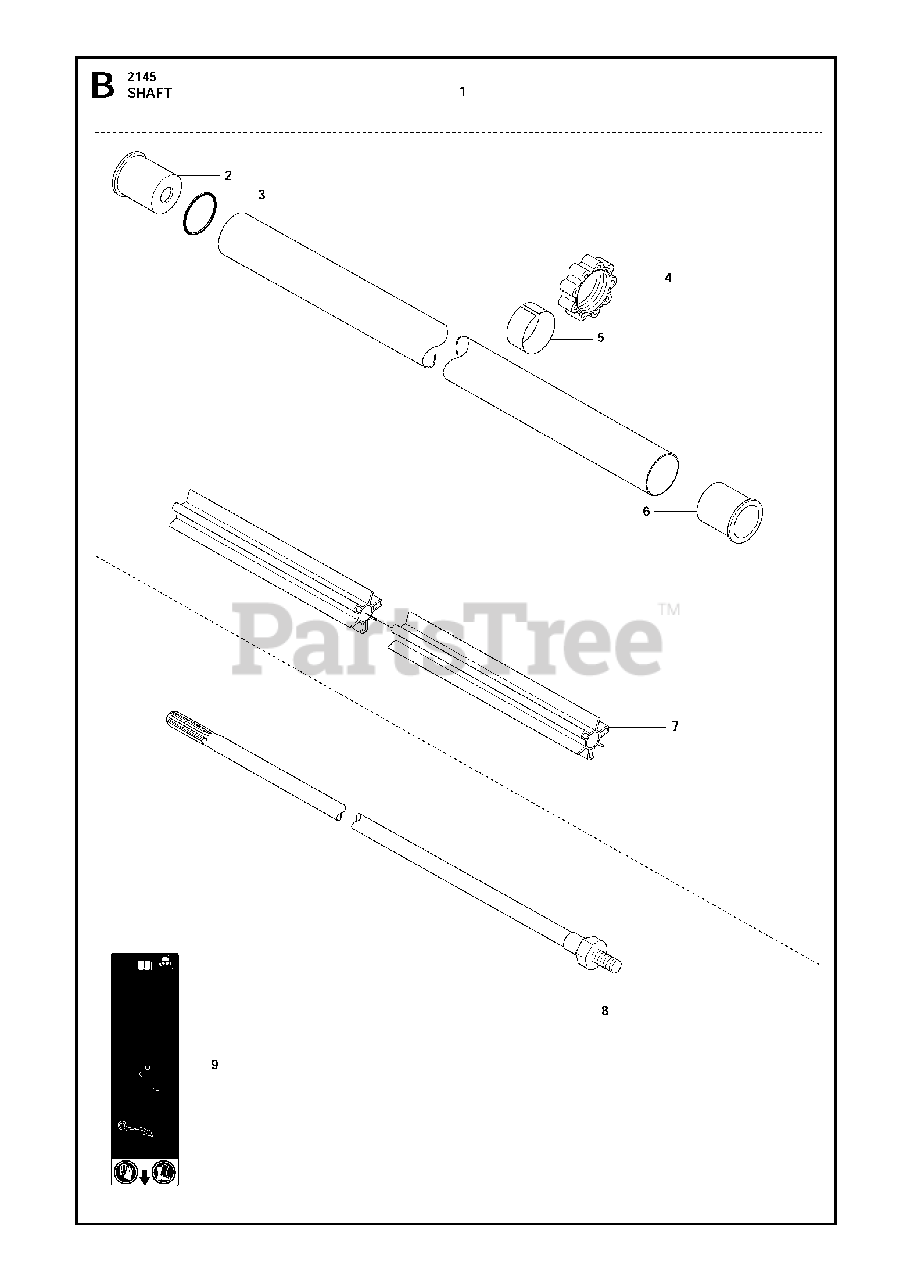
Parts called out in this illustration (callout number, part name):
1	TUBE
1	RP DRIVE SHAFT TUBE
2	SPACER SLEEVE
4	MOVEMENT LIMITER
5	%BAND
6	SPACER SLEEVE
7	GUIDE
8	SHAFT
8	DRIVE SHAFT
9	WARNING DECAL
